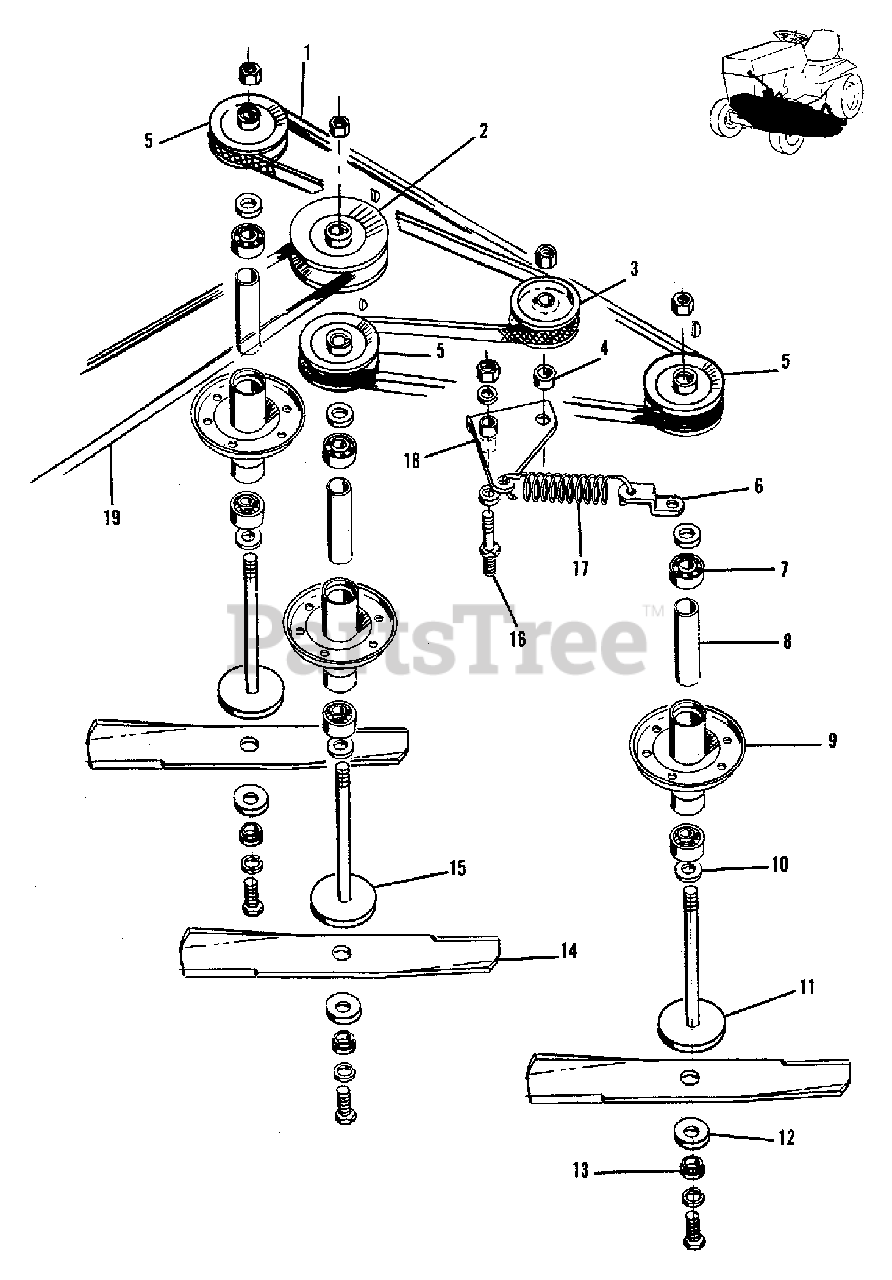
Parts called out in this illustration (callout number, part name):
1	*V-BELT, Arbor Drive
1	**V-BELT, Arbor Drive
2	*SHEAVE, Top Center (Smaller Hub - O.D. Of 1-3/8")
2	*SHEAVE, Top Center (Larger Hub - O.D. Of 1-5/8")
3	PULLEY, Idler
3	CAPSCREW, 3/8NC x 1-3/4
3	WASHER, Plain, 13/32 x 7/8 x #14
3	LOCKWASHER, 3/8
3	NUT, 3/8NC
4	SPACER, Pulley & Lever
5	SHEAVE, Center & Outer
5	WASHER, Plain, 25/32 X 1-1/4 x #7 (Between Sheaves On Center Arbor)
5	KEY, Woodruff, 3/16 x 5/8
6	CLIP, Spring Anchor
7	BEARING, Ball
8	SPACER, Tube Assembly
9	TUBE ASSEMBLY, Arbor
9	CAPSCREW, 5/16NC x 3/4
9	WASHER, Plain, 38 x 7/8 #16
9	LOCKWASHER, 5/16
9	NUT, 5/16NC
10	WASHER, Special
11	ARBOR ASSEMBLY, Left & Right
11	NUT, Lock, Jam, 3/4NF
12	WASHER, Spring
13	WASHER, Shouldered
13	CAPSCREW, 7/16NF x 1-1/2, GR8
13	LOCKWASHER, 7/16
14	*BLADE, Knife
14	**BLADE, Knife
15	ARBOR ASSEMBLY, Center
15	NUT, Lock, Jam 3/4NF
16	STUD, Idler
16	WASHER, Plain, 13/32 x 1-1/4 x #16
16	LOCKWASHER, 3/8
16	NUT, 3/8NC
16	NUT, Lock, 3/8nc
16	WASHER, Plain, 13/32 x 7/8 x #14
17	SPRING, Lever
18	LEVER ASSEMBLY, Idler
19	*V-BELT, PTO, Front
19	**V-BELT, PTO, Front
